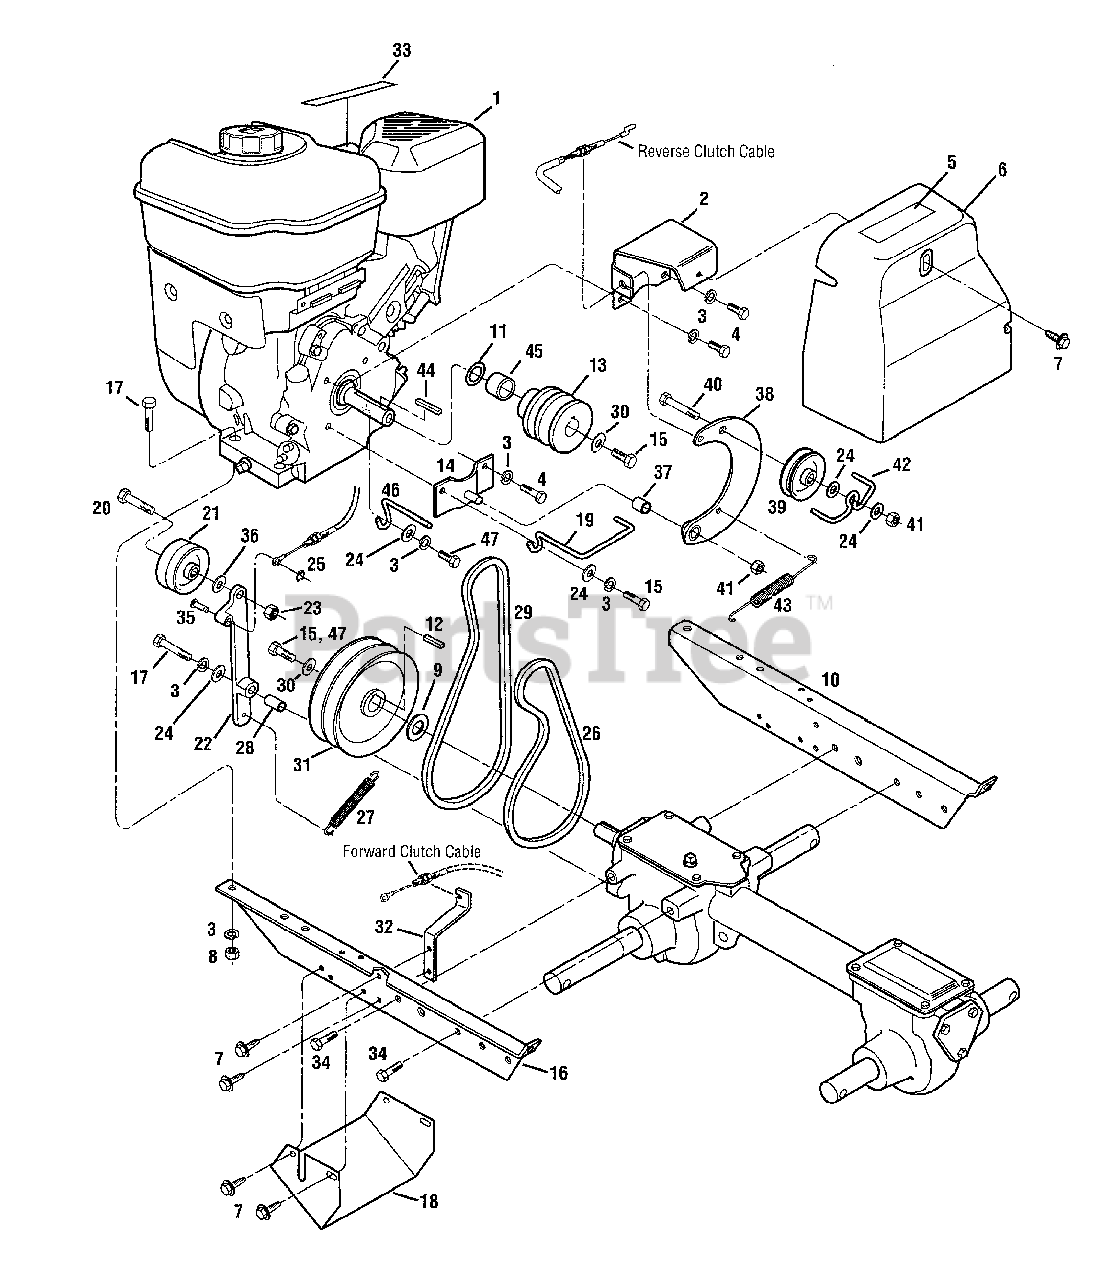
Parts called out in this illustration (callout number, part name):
1	Engine, Recoil Start
2	Bracket, Belt Cover
3	Lockwasher, 5/16
4	Hex Hd. Screw, 5/16-24 x 1/2
5	Decal, Hot Surfaces Warning
6	Belt Cover
7	Flange Screw, Self-Tapping, 1/4-20 x 1/2
8	Hex Nut, 5/16-18
9	Support Washer
10	Engine Bracket, Right
11	Shim
12	Key, 3/16" x 1"
13	Pulley, Engine Drive
14	Reverse Idler Bracket
15	Hex Screw, 5/16-24 x 1
16	Engine Bracket, Left
17	Hex Screw, 5/16-18 x 1-1/2
18	Guard, Belts/Pulleys
19	Forward Belt Guide
20	Hex Screw, 3/8-16 x 1-1/2
21	Forward Idler Pulley
22	Forward Idler Lever
23	Locknut, 3/8-16
24	Flat Washer
25	Klip Ring
26	Forward Drive Belt
27	Forward Return Spring
28	Bushing, Forward Idler Lever
29	Reverse Drive Belt
30	Belleville Washer
31	Transmission Pulley
32	Bracket, Cable Mounting
33	Decal, Stabilization
34	Hex Screw, 5/16-18 x 5/8
35	Clevis Pin
36	Flat Washer, 3/8
37	Bushing
38	Reverse Idler Arm
39	Pulley, Reverse Idler
40	Hex Screw, 5/16-18 x 2
41	Locknut, 5/16-18
42	Belt Guide
43	Reverse Return Spring
44	Key, 3/16 x 1-1/2
45	Spacer
46	Forward Belt Guide
47	Hex Hd. Screw, 5/16-24 x 3/4
